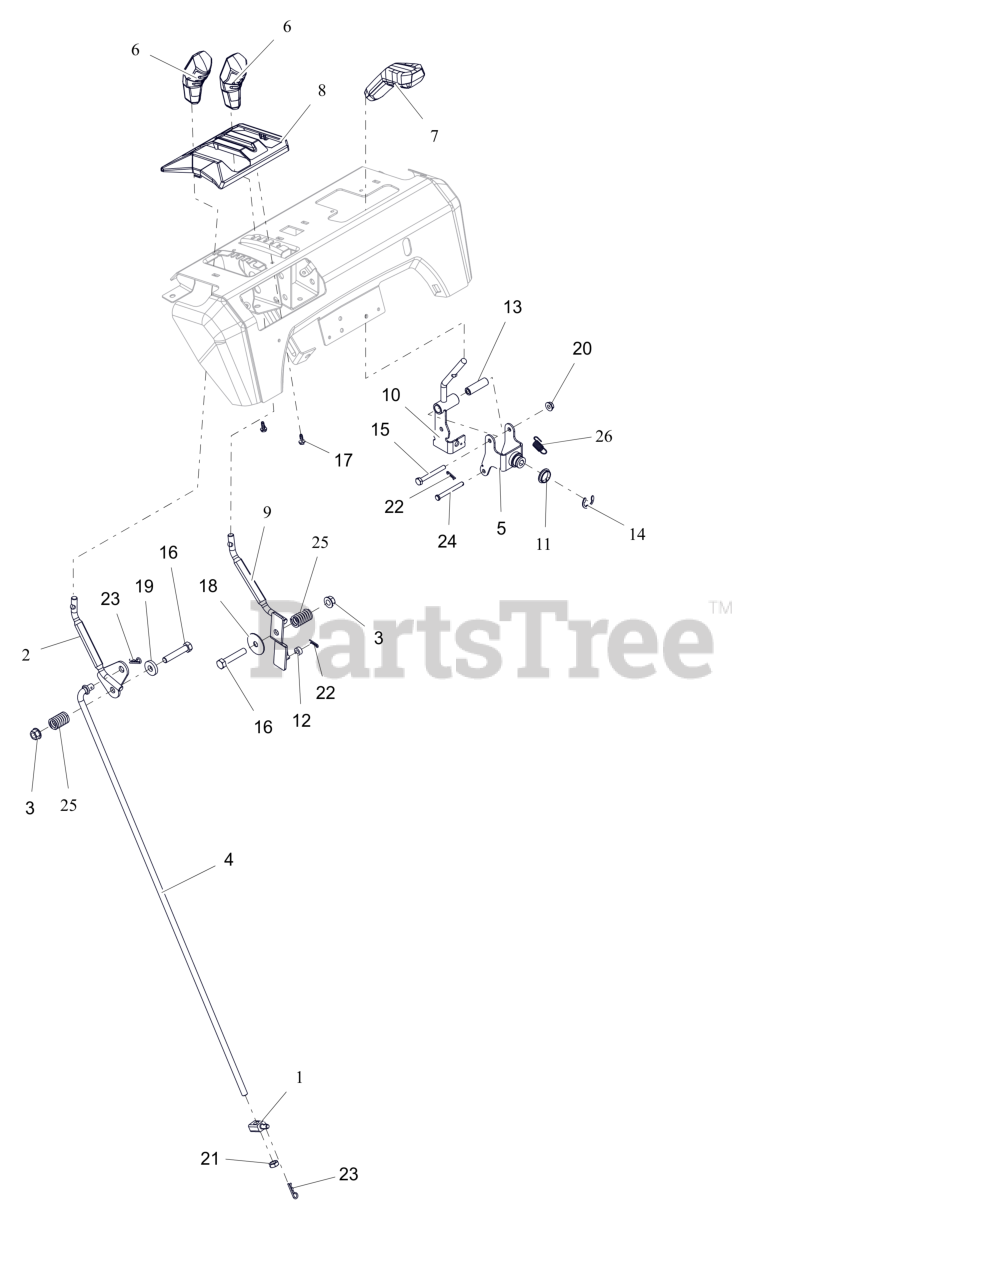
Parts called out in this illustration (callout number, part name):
1	PIVOT,SHIFT ROD .375-16(TRUNN)
2	WELDMENT,LG DASH SPEED CONTROL
3	NUT-LK-TOP-FLG .38-16 ZC120
4	ROD, SHIFT - LARGE DASH DELUXE
5	WELDMENT, CONTROL BRACKET
6	KNOB, CONTROL
7	HANDLE, QUICK TURN
8	BEZEL, SHIFT - FRICTION
9	WELDMENT,LG DASH DEFL CONTROL
10	WELDMENT, CONTROL LEVER
11	BUSHING, POLYLINER-.75 SNAPIN
12	BSHG-SLV .265X.500X.219
13	BSHG, SLV .265X.505X1.665
14	E-RING .750X.050
15	BLT,HEX .25-20X2.25 G5 ZCC
16	BLT,HEX .38-16X2.00 G5 ZCC
17	SCR, PLASTIC #10X.50
18	WSHR,FLT .380X1.50X.062 ZCC
19	WSHR, FLT .406X1.00X.188 ZCC
20	NUT-LK-CTR-FLG .25-20 ZC120
21	NUT-JAM .375-16 G2 ZCC
22	PIN, HAIR #178 .06X.77 ZCC
23	PIN, HAIR #213 .08X1.19 ZCC
24	PIN, CLEVIS - .25 X 2.25 ZCC
25	SG-COMP .125X.781X1.250
26	SPRING-EXT .047X.438X1.45
